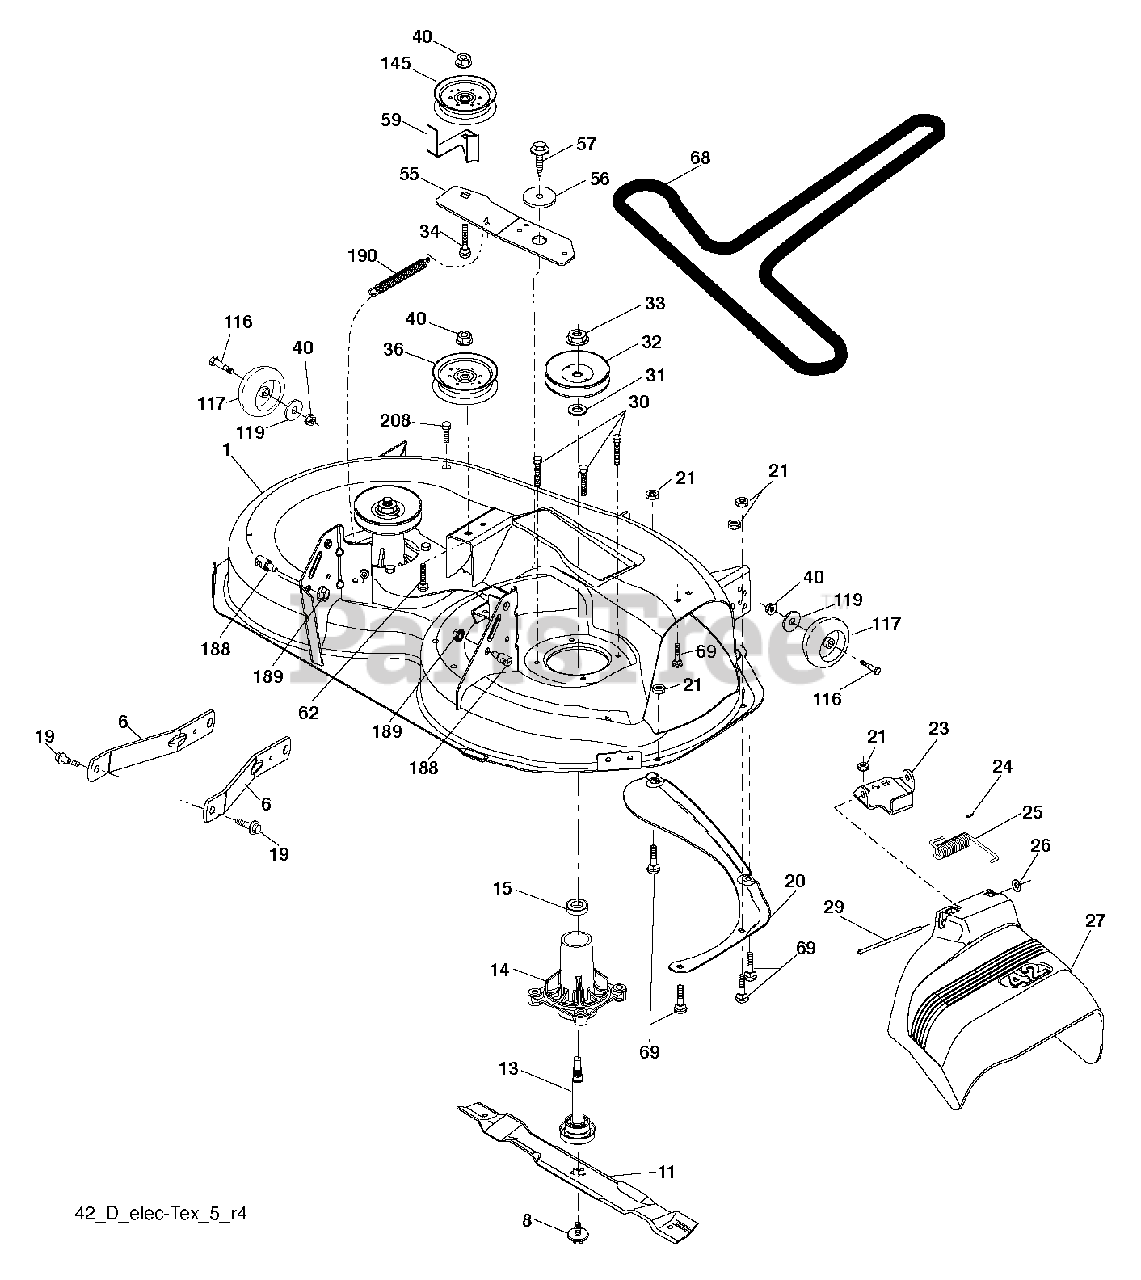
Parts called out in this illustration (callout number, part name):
1	DECK.WELDMENT.42"
6	ARM.SUSPENSION.MOWER.R
8	BOLT.WASHER.ASM.7/16-2
11	42" HI-LIFT BLADE
13	SHAFT.ASM.MDRL.N/GREASE.38
14	HOUSING.MANDREL.4PT.
19	BOLT.SHOULDER
20	BAFFLE.VORTEX
21	LOCKNUT
23	BRKT.DEFLECTOR.38"2005+
24	CAP-SLEEVE LT
25	SPRING.TORSION.DEFLECT
26	NUT PUSH M
27	SHIELD.DEFLECTOR.MOWER.42"BLAC
29	ROD.HINGE
30	SCREW, WASHER HEAD
31	WASHER.SPACER.MANDREL
32	PULLEY/MANDREL
33	NUT.FLANGE.LOCK.TOP
34	BOLT.3/8-16X1.50
36	PULLEY.IDLER.2006
40	NUT LOCK FLG 3/8-16 UNC
55	IDLER.ARM.42"
56	SPACER.RETAINER
57	SCREW 3/8-16X1
59	GUARD, BELT
68	BELT V SECONDARY
69	BOLT
116	BOLT M
117	WHEEL.GAGE.HALF.SPOKED
119	WASHER
145	PULLEY.IDLER.48"PRIMARY
188	STUD.FASTNER.W/ANTI-ROTATE
189	NUT LOCK HEX FLANGE 5/16-18
190	SPRING.MOWER.DRIVE.ELECTRIC
208	SCREW 3/8-16X1/2
